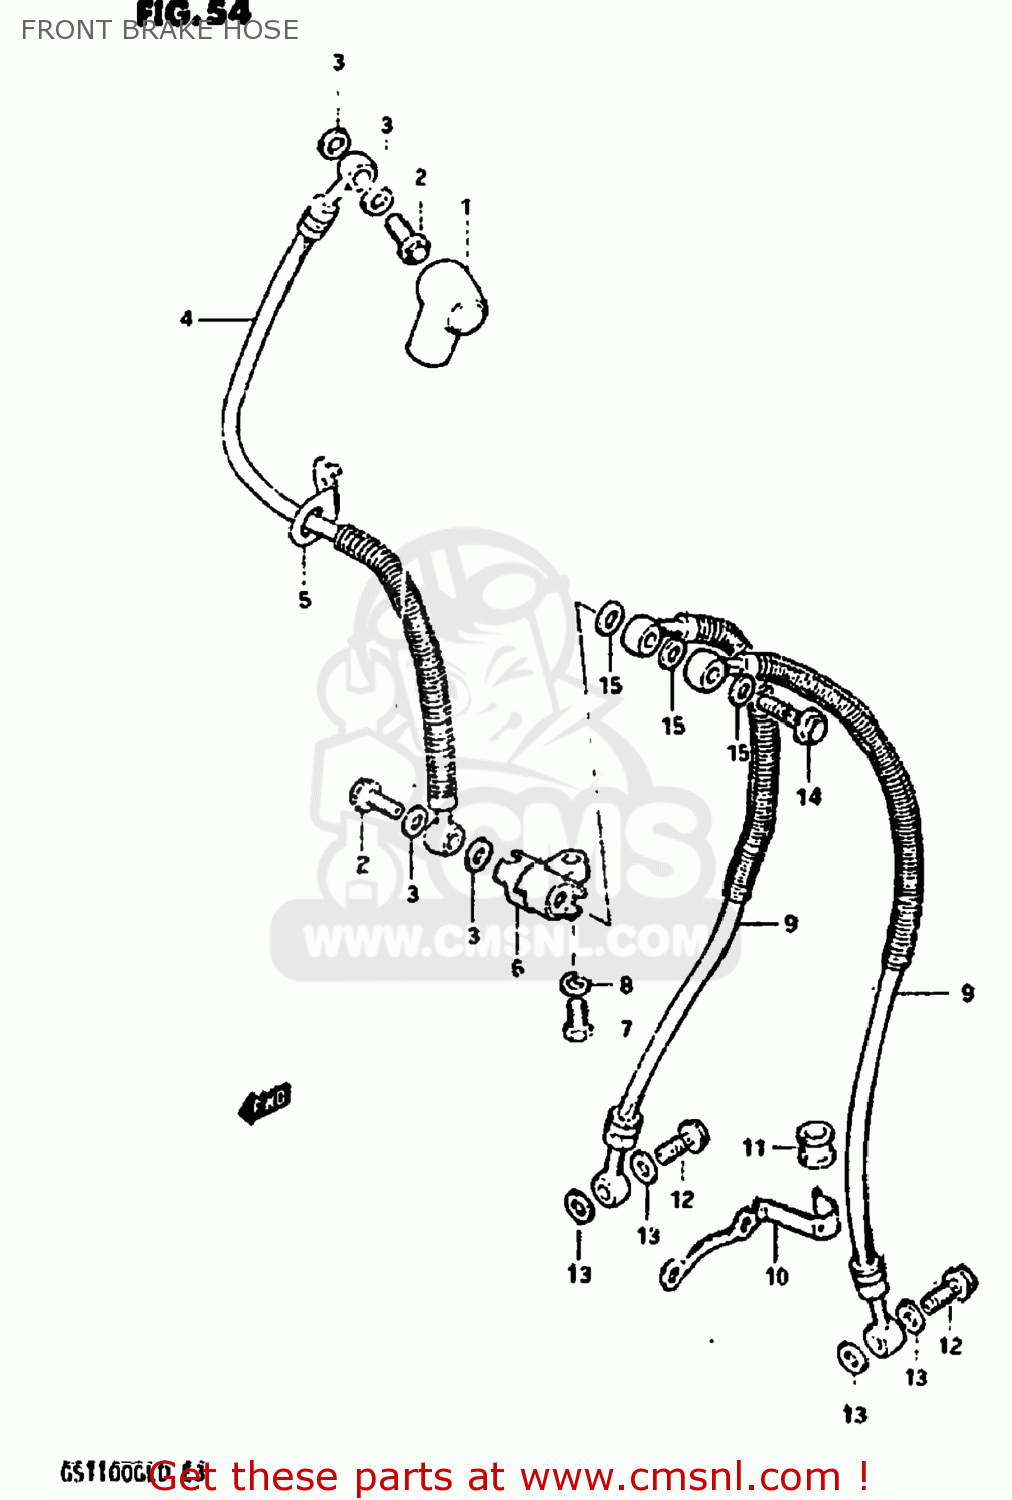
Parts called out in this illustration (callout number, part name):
1	BOOT,MASTER CYLINDER
2	BOLT,UNION
3	WASHER
4	HOSE,FRONT BRAKE NO.1
5	GUIDE,BRAKE HOSE NO.1
6	JOINT,BRAKE HOSE
7	BOLT
8	LOCK WASHER
9	HOSE,FR BRAKE NO.2,L
10	GUIDE,BRAKE HOSE NO.2
11	BUSH,BRAKE HOSE GUIDE,NO.2
12	BOLT,UNION
13	WASHER
14	BOLT,UNION
15	WASHER
